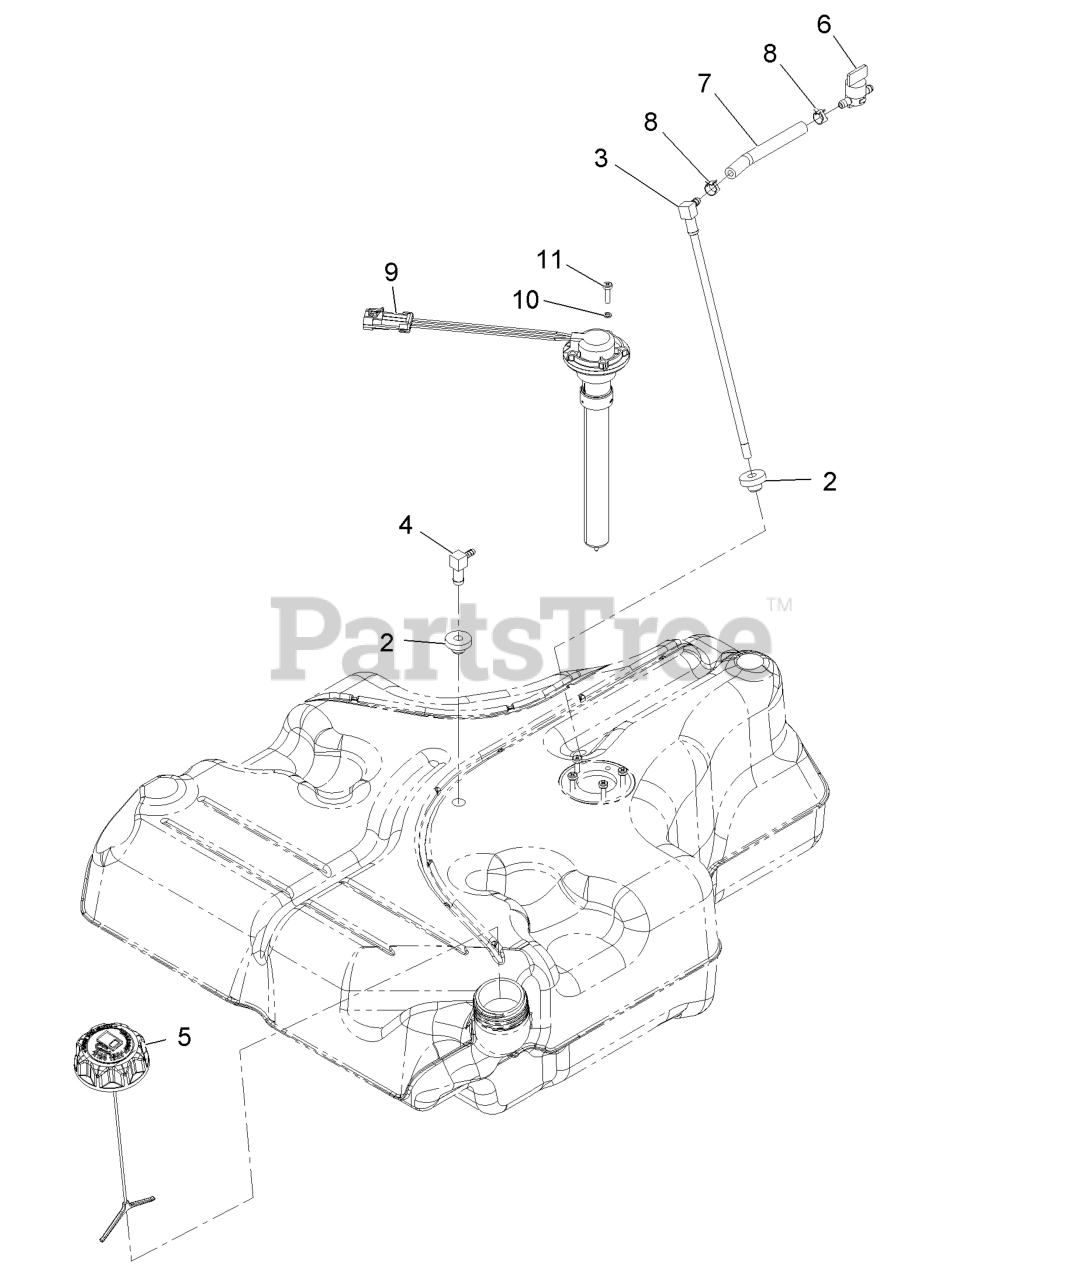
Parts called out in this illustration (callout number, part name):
2	BUSHING
3	FUEL LINE KIT (WITH GROMMET)
4	FITTING-90 ELBOW
6	VALVE-FUEL
7	HOSE-FUEL
8	CLAMP-HOSE
10	WASHER-LOCK
11	SCREW-PAN
